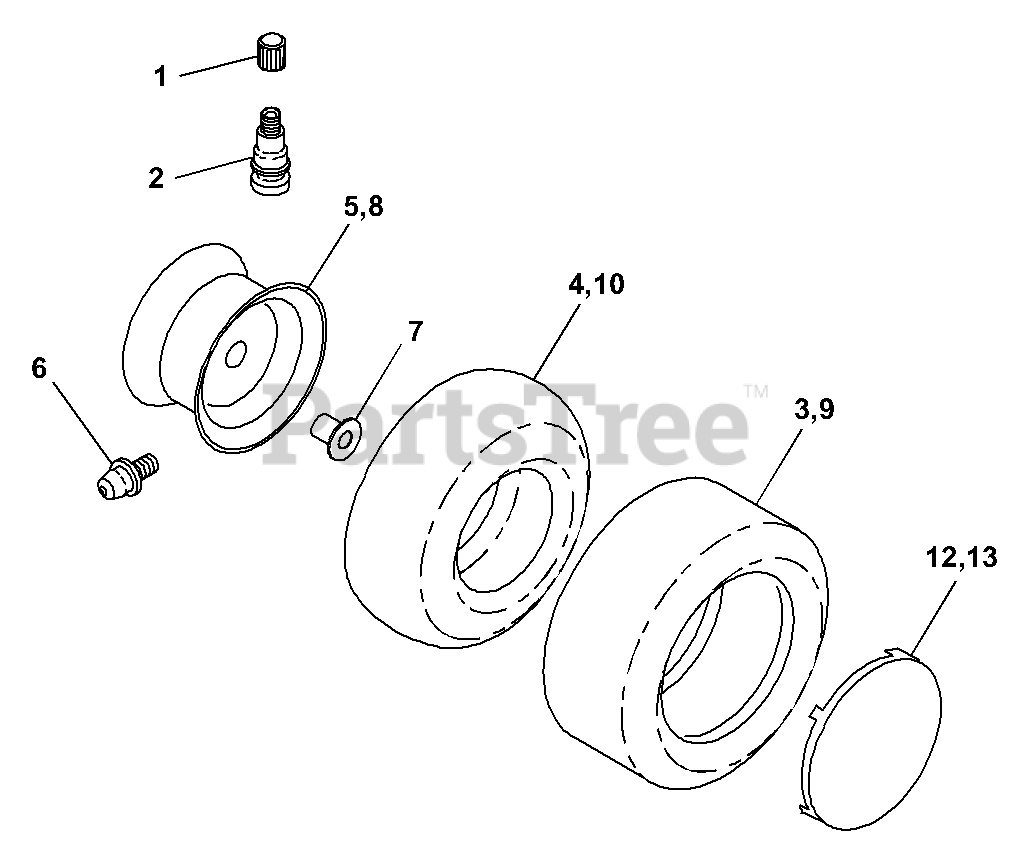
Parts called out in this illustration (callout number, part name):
1	Cap Valve Tire
2	Stem Valve
3	Tire F Ts 15 X 6 0 - 6 Service
4	Tube Front
5	Rim Asm 6" front White Service
6	Fitting Grease
7	Bearing Flange
8	Rim Asm 8"rear White Service
9	Tire R Ts 20 10 C Service
10	Tube Rear
12	Cover Wheel 6"white
13	Cover Wheel 8"white
